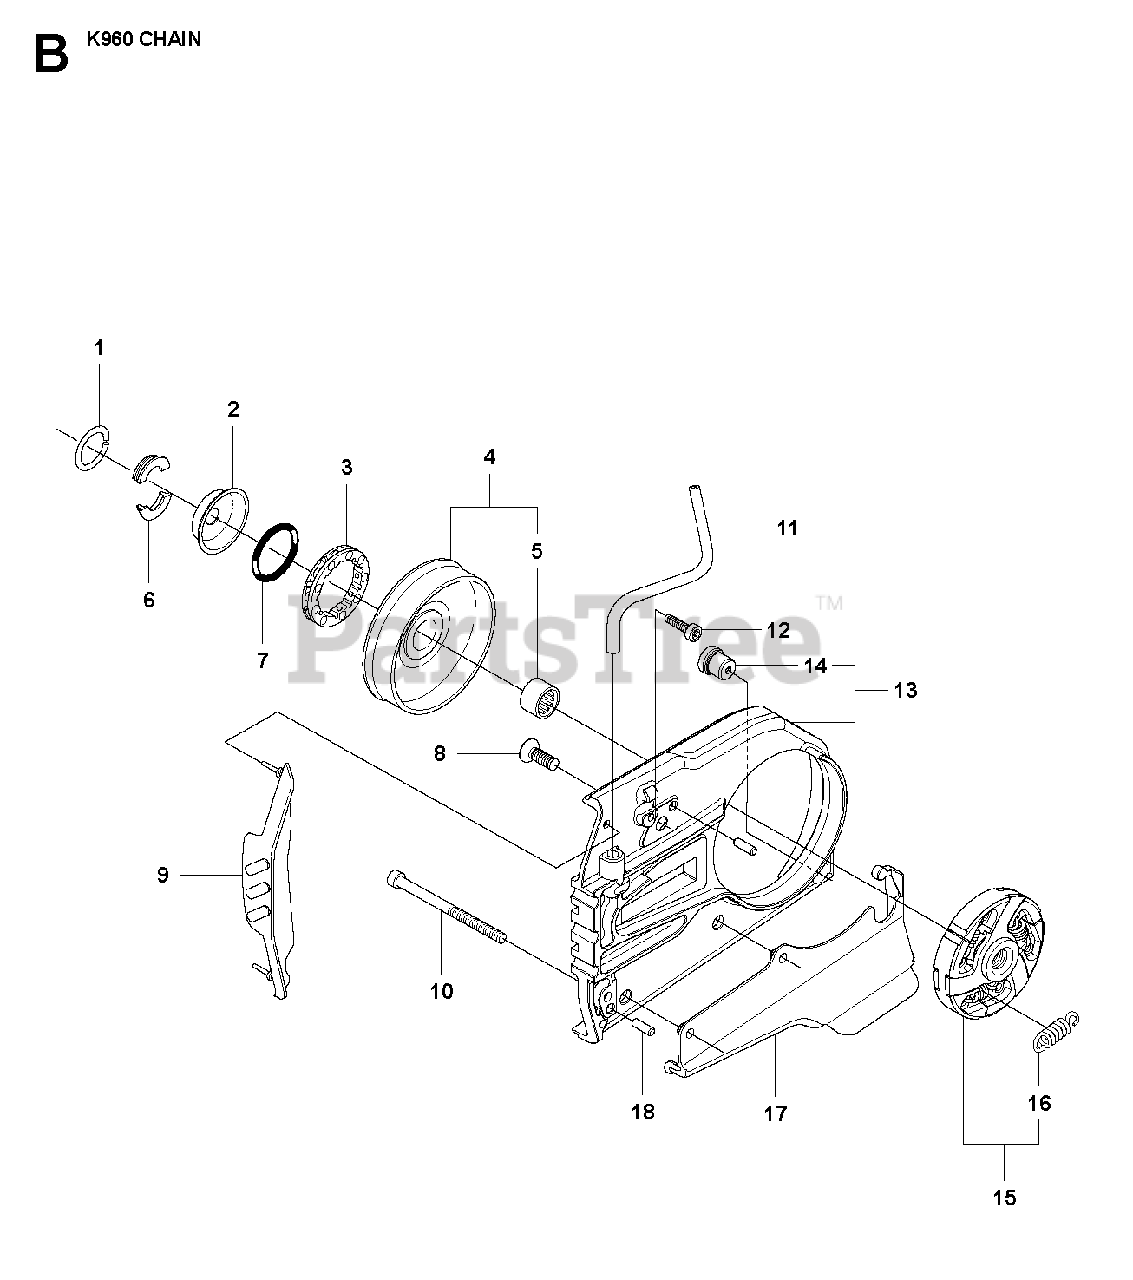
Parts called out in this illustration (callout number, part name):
1	RETAINER RING
5	NEEDLE BEARING
10	SCREW ITXSCM
12	SCREW ITXSCM
16	CLUTCH SPRING
18	PARALLEL PIN
